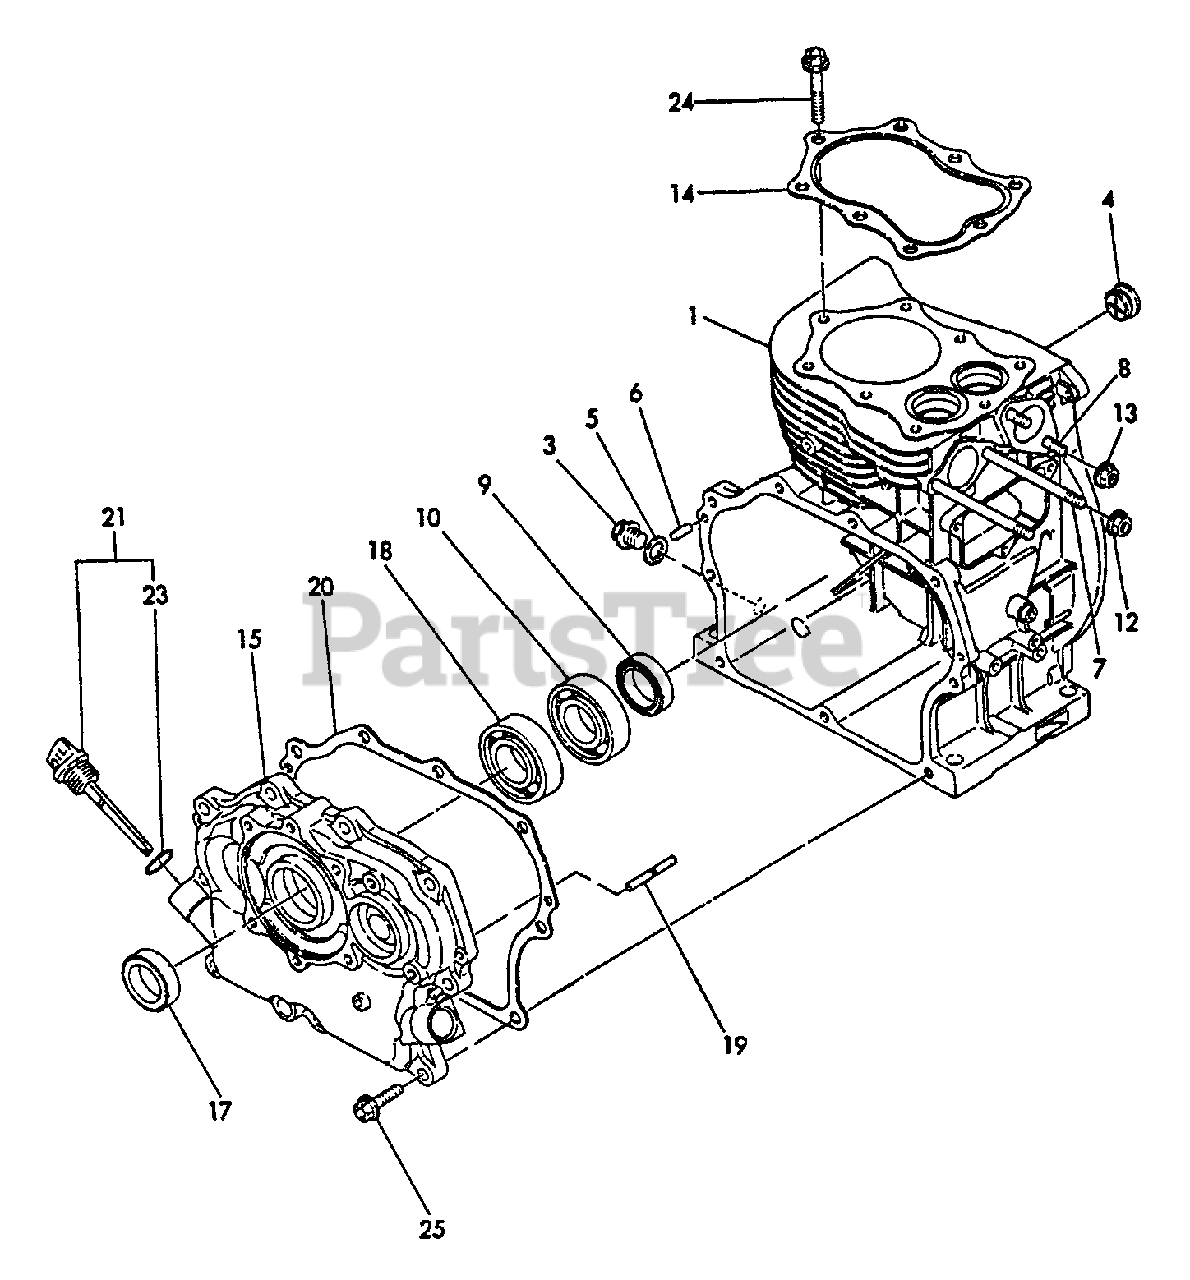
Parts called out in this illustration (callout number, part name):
1	CYLINDER BLOCK SET
3	PLUG, DRAIN
4	PLUG
5	GASKET
6	PIN - 6X16
7	STUD - 8X95 -- PLATED
8	STUD -- PLATED
9	SEAL, OIL
10	BEARING, BALL - 6206C4
12	NUT - 8
13	NUT - 8
14	GASKET, CYLINDER
15	COVER, CRANKCASE
17	SEAL, OIL
18	BEARING, BALL - 6206C4
19	SHAFT, GOVERNOR
20	GASKET, CRANKCASE
21	CAP ASSY
23	O-RING - 18
24	BOLT - 8X50
25	BOLT - 8X30 -- PLATED
